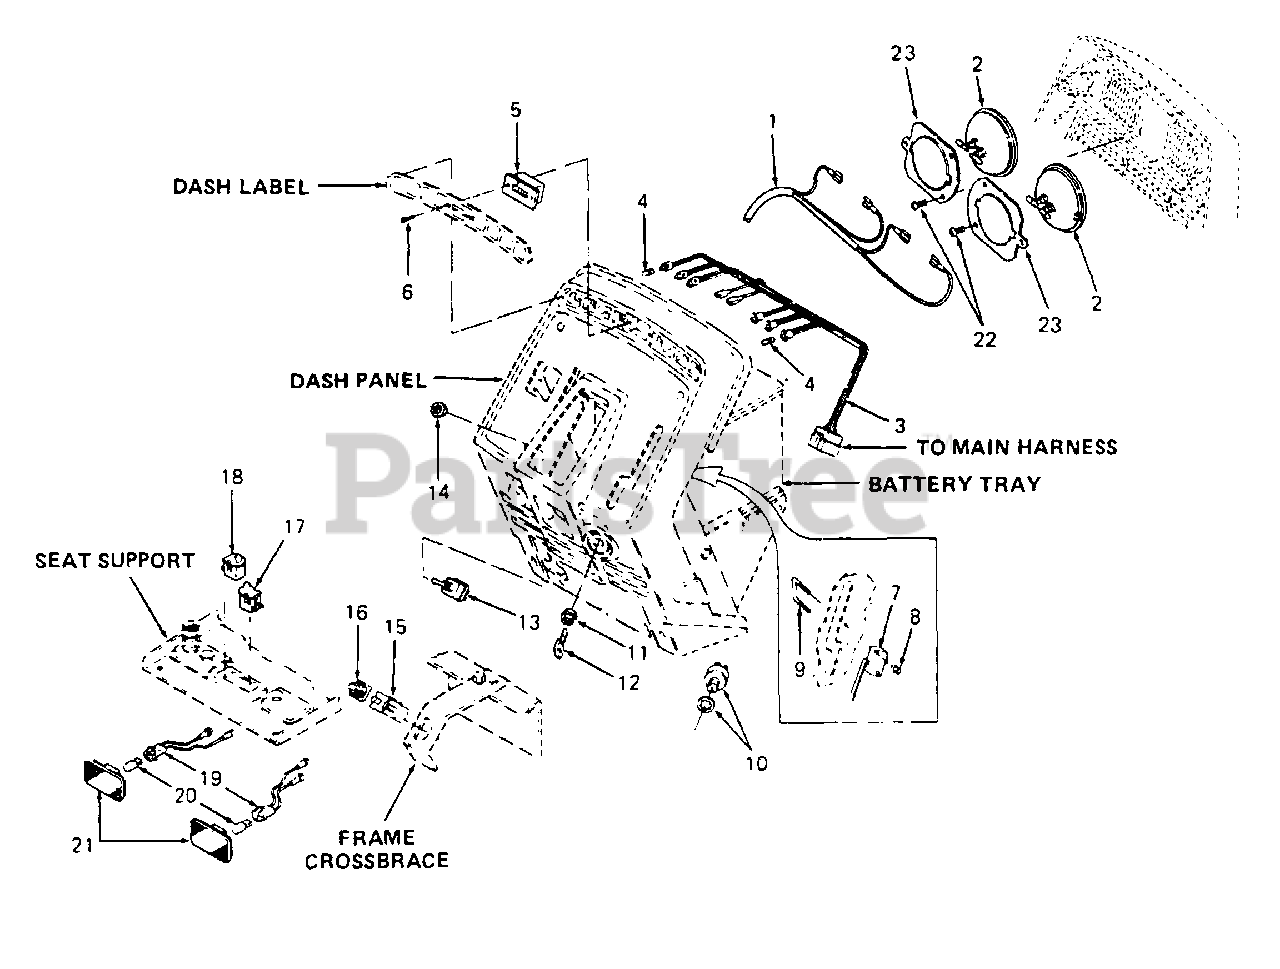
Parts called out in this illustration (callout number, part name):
1	Harness, Main Wire
2	Head Lamp, Sealed Beam
3	Harness, Indicator Wire
4	Bulb, Indicator
5	Hour Meter
6	Screw, Truss Hd Tapp, #6 x .62 Lg
7	Switch, Reverse
8	Nut, Hex Insert Lock, #4-40
9	Screw, Switch
10	Switch, Ignition
11	Nut, Ignition Switch
12	Key, Ignition
13	Switch, PTO
14	Nut, Hex, 1/2-27 x .100 Thk
15	Switch, Interlock
16	Boot, Switch
17	Switch, Snap Mount
18	Switch, Snap Mount
19	Cable Assy, Tail Light
20	Bulb, Tail Light
21	Lens Assy, Tail Light
22	Screw, Pan Hd Tapp, #12 x .50 Lg
